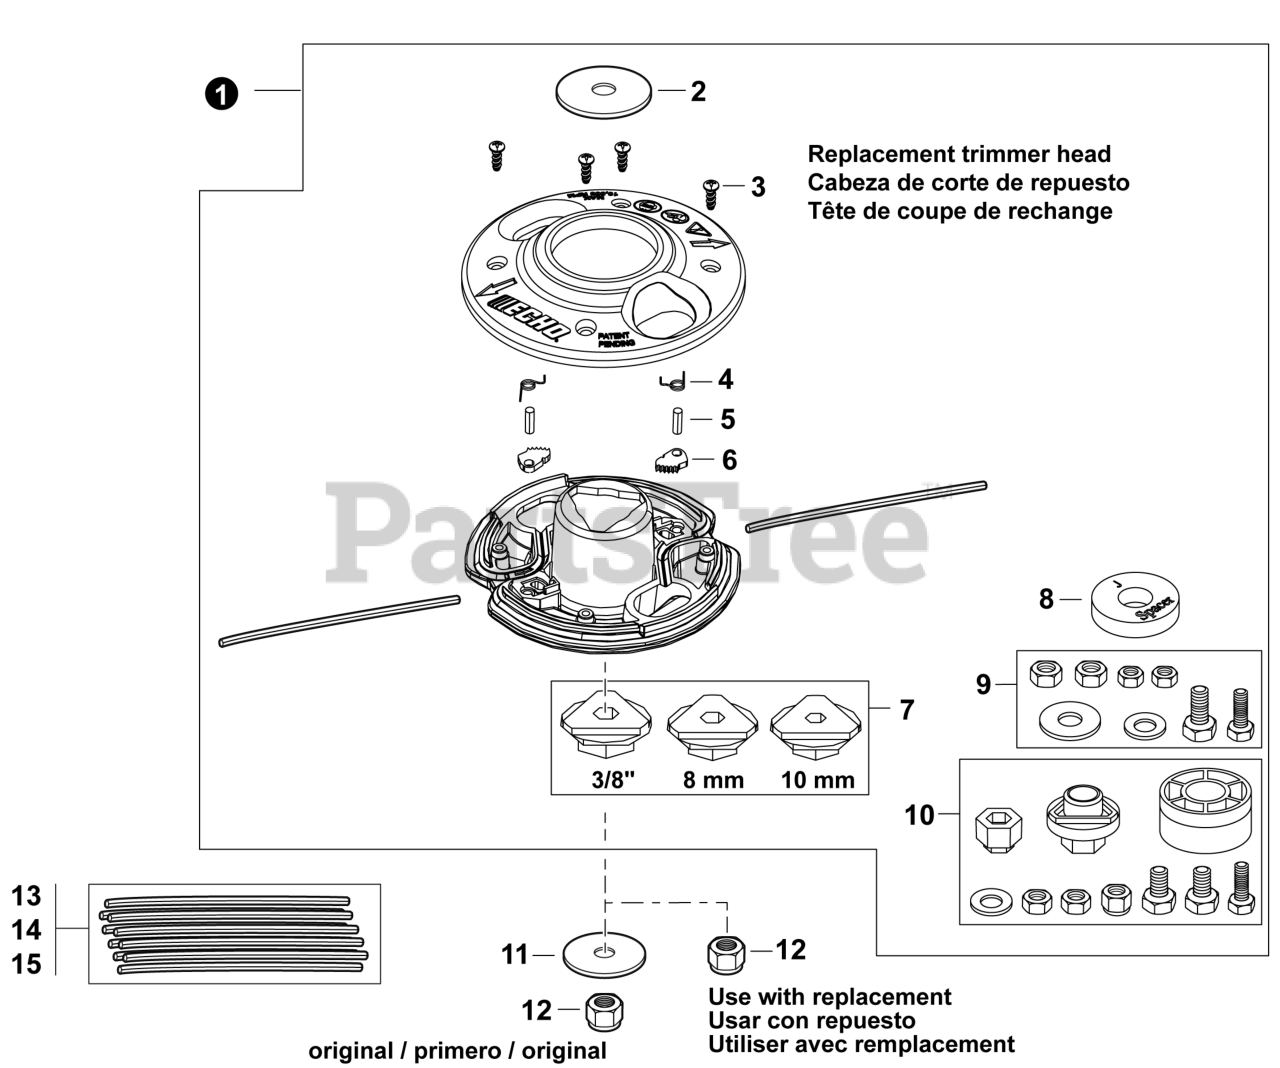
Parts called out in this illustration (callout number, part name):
1	TRIMMER HEAD - RAPID-LOADERT
2	WASHER 10
3	SCREW, TAPPING #8x0.5
4	SPRING, TORSION
7	ADAPTOR KIT
9	HARDWARE PACK
10	HARDWARE PACK
11	WASHER 10
12	NUT, LOCK
13	LINE, TRIMMER - 0.095 DIA. (PKG. OF 10)
14	LINE, TRIMMER - 0.095 DIA. (PKG. OF 20)
15	LINE, TRIMMER - 0.095 DIA. (PKG. OF 50)
